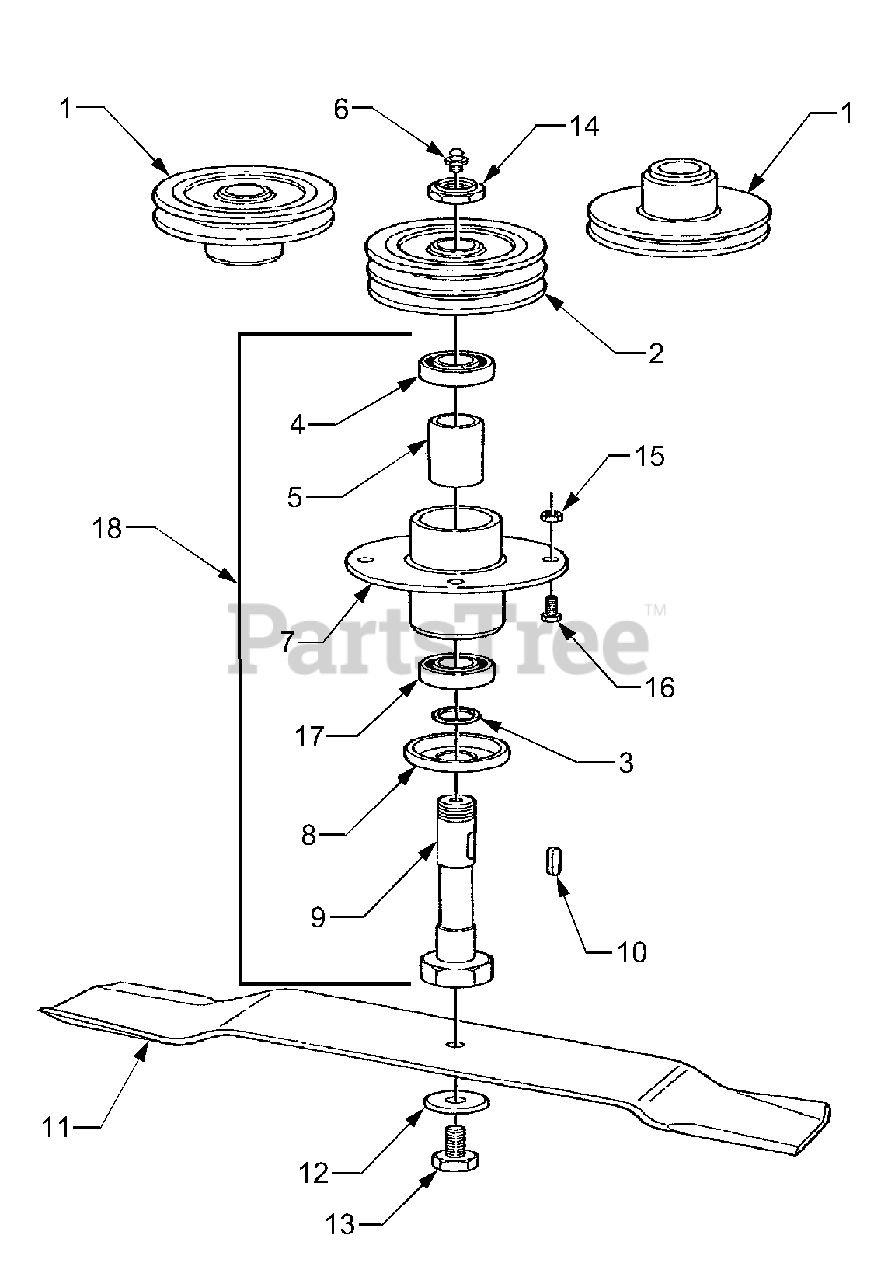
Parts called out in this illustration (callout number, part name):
3	Spacer Washer
6	Grease Fitting
9	Blade Shaft
11	Blade - Standard Lift
12	Spring Washer
16	Bolt, 10 x 30
18	Spindle Assembly - Complete
